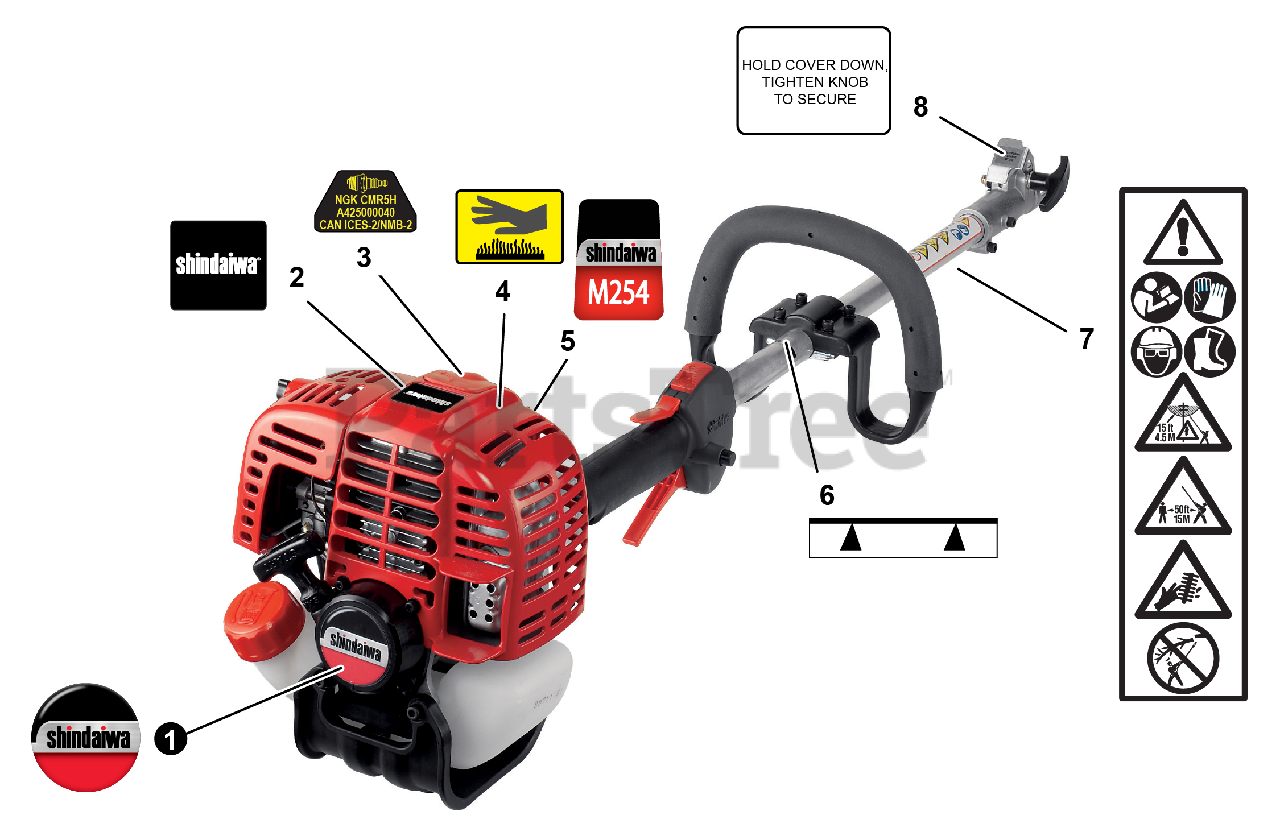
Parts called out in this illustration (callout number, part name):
1	LABEL, RECOIL STARTER
2	LABEL, SHINDAIWA
3	LABEL, SPARK PLUG - CMR5H
4	LABEL, CAUTION - HOT
5	LABEL, M254
6	LABEL - ALIGNMENT
7	LABEL, CAUTION
8	LABEL, LATCH INSTRUCTION
